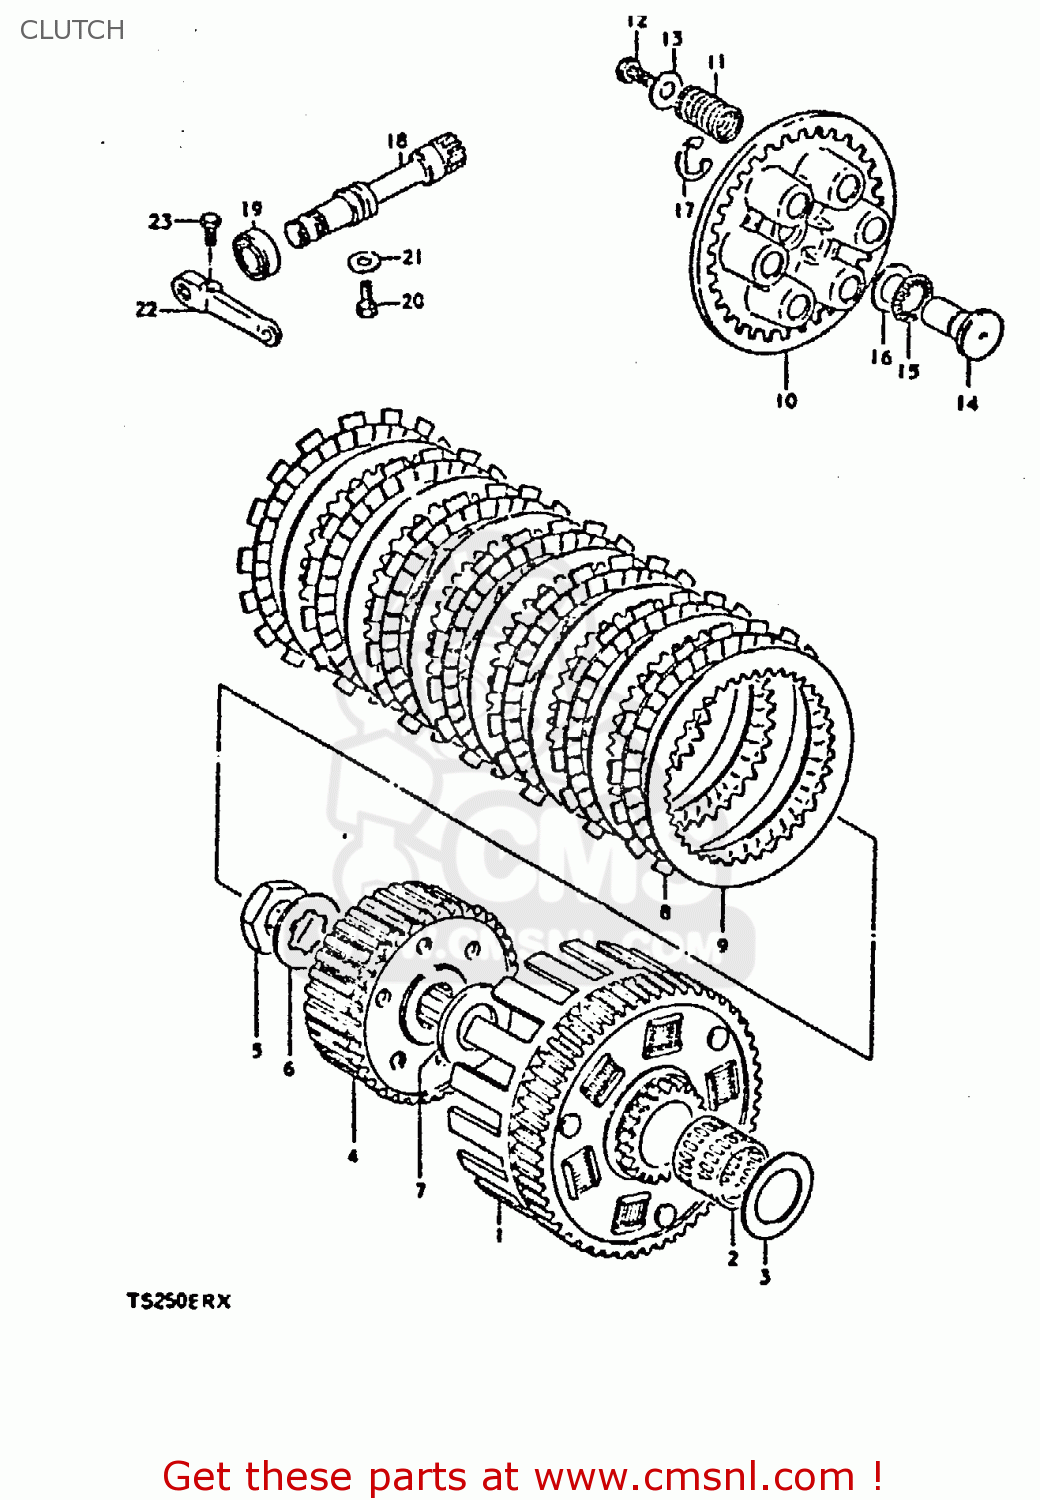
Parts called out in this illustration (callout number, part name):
1	GEAR ASSEMBLY,PRIMARY DRIVE
2	ROLLER BEARING (25X30X3
3	WASHER(25X41X3)
4	HUB,CLUTCH SLEEVE
5	NUT (20MM)
6	WASHER,LOCK
7	WASHER(20X44X3)
8	PLATE,CLUTCH DRIVE (MCA)
9	PLATE,CLUTCH DRIVEN(T:2.0) (NAS)
10	DISC,CLUTCH PRESSURE
11	SPRING
12	BOLT
13	14
14	RACK,CLUTCH RELEASE
15	BEARING(15X28X2)
16	WASHER
17	E RING 12MM
18	PINION,CLUTCH RELEASE
19	OIL SEAL
20	BOLT(6X12)
21	WASHER
22	ARM,CLUTCH RELEASE
23	BOLT
